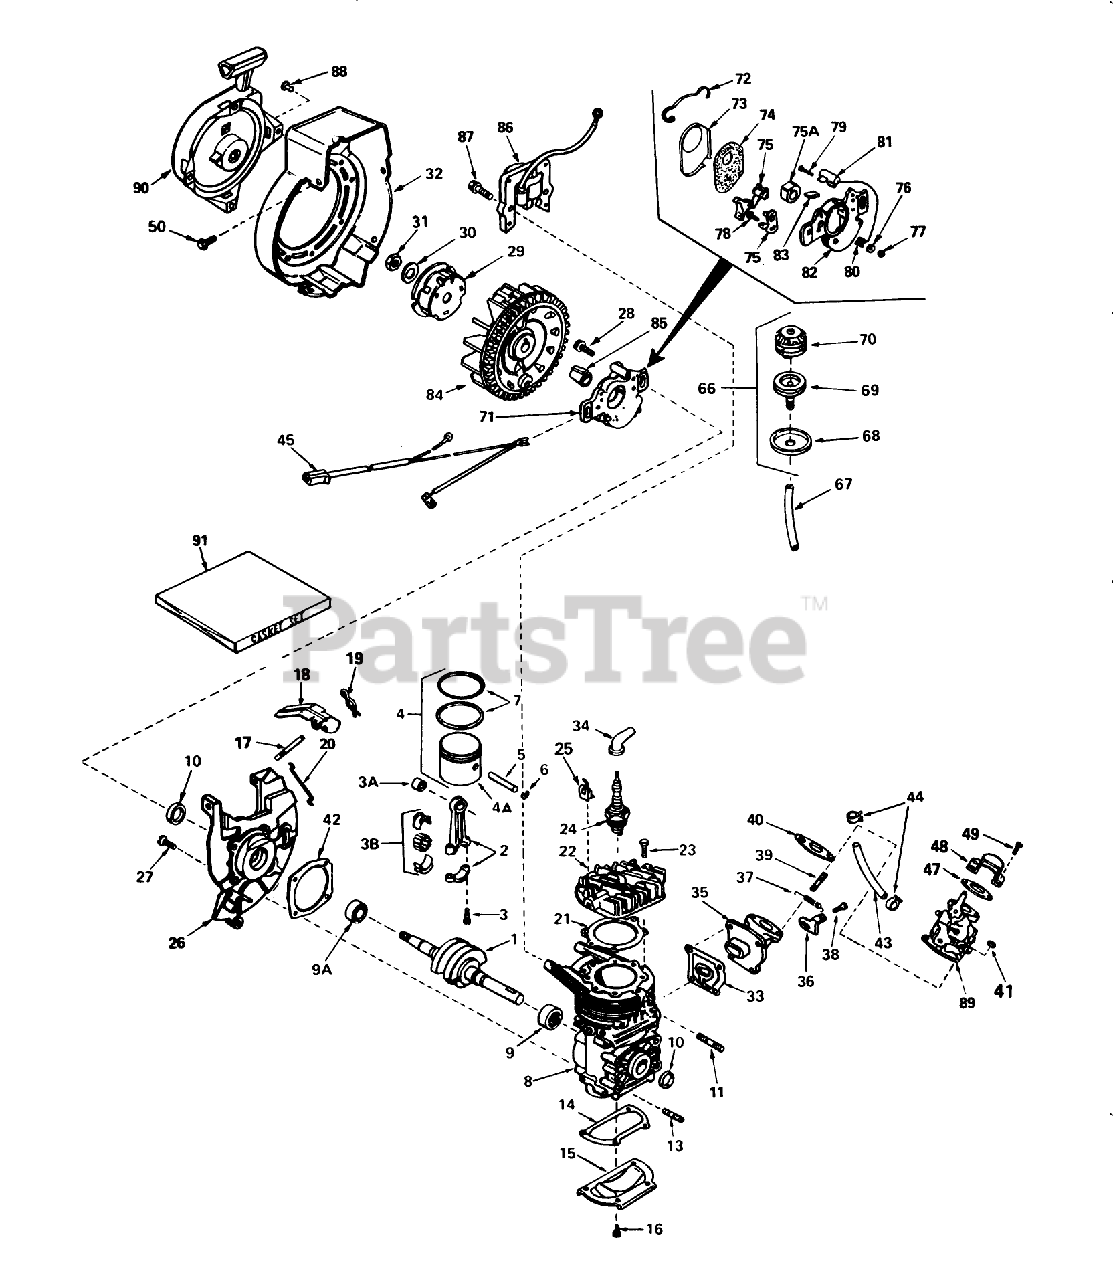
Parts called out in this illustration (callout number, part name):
1	Crankshaft
2	Rod Assembly, Connecting (Incl. #3, 3A 3B)
3	Bolt-Rod, Connecting
3A	Bearing-Cartridge
3B	Bearing Liner Set Needle
4	Piston, Pin Ring Assy. (Incl. Ref. #6 thru 9)
4A	Piston
5	Pin, Piston
6	Ring-Retaning
7	Ring Set
8	Block Assy., Cylinder (Order short block if replacement is required)
9	Bearing-Cartridge
9A	Bearing-Ball
10	Seal-Oil
14	Gasket, Cover
15	Plate, Cover
16	Screw (T-25, 10-24 x 1/2)
17	Shaft, Air Vane
18	Vane Assy., Air
19	Clip,Air Vane
20	Link-Governor
21	Gasket, Head
22	Head-Cylinder
23	Screw (T-30, 1/4-20 x 3/4)
24	Head Adjustment Knob
26	Base Assy., Blowerr Housing (Incl. Ref. #10 17)(used on type 1603, 1603A 1603B)
27	Screw
28	Screw, Hex Washer Hd.
29	Cup-Starter
30	Washer-Spring
31	Nut-Flywheel
32	Housing-Blower
33	Gasket, Port
34	Cover-Spark Plug
35	Elbow Assy., Adapter
36	Lever, Adjusting
37	Spring, Adjusting Lever
38	Screw
39	Stud Carburetor
40	Gasket, Carburetor
41	Locknut
42	Gasket, Shroud Base
43	Line-Fuel
44	Clamp-Line, Fuel
45	Harness, Wire
47	Gasket
48	Baffle-Carburetor
49	Screw
50	Screw-Hex, Hd.
66	Primer Assy.
67	Line, Primer
68	Retainer, Primer Bulb
69	Body, Primer
70	Bulb-Primer
71	Stator Plate Assy. (incl. Nos. 107, 111 thru 118 120)
72	Spring Breaker Box
73	Cover-Dust
74	Gasket Dust
75	Breaker Assy.
75A	Cam, Breaker
76	Washer
77	DECAL
78	Breaker Screw
79	Condenser Screw
80	Terminal, Ground
81	Condenser
82	Stator Plate
83	Felt,Cam Wiper
84	FIywheel
85	SHIELD
86	Lamination Coil Assy. (Incl. No. 42)
87	Screw
88	Rivet, Pop (3/16" dia.)(Can be purchased locally)
89	Carburetor (Incl. Ref. #40)
90	Starter-Rewind
91	Gasket Set (Incl. items marked *)
